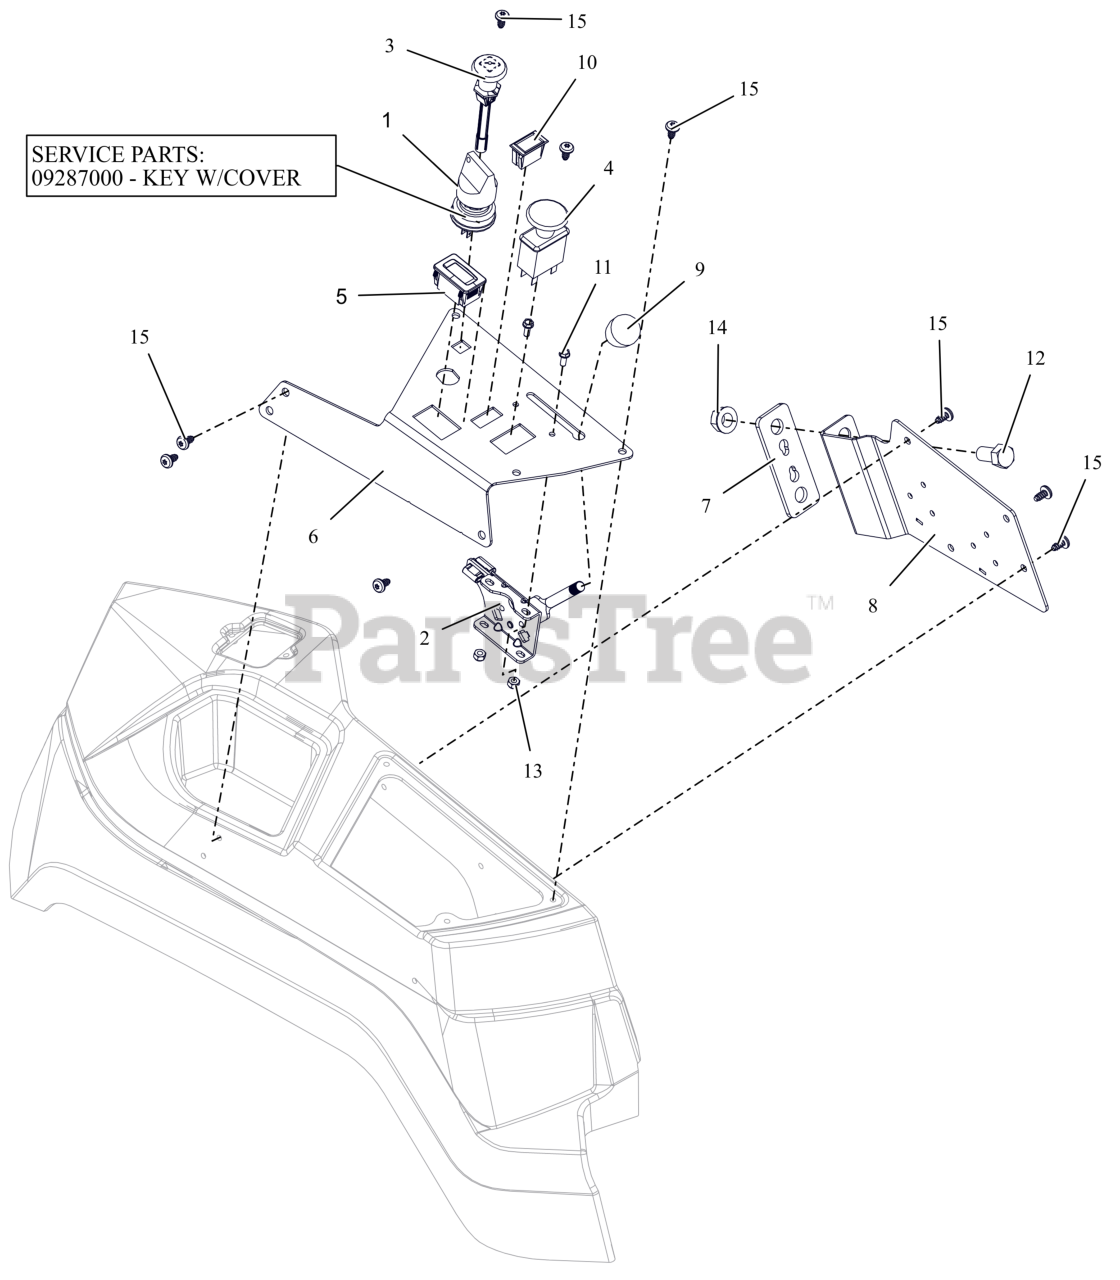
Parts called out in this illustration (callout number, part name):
1	SWITCH, IGNITION
1	KEY, W/ SHIELD
2	CABLE, PRO THROTTLE CONTROL
3	CABLE - CHOKE, SNAP-IN
4	SWITCH, CLUTCH
5	HOUR METER
6	PLATE, APEX CONTROL PANEL
7	PLATE, CONTROL PANEL SPACER
8	BRKT, FENDER/RELAY MOUNTING
9	KNOB-CONTROL-BLACK .38-16X.50
10	SWITCH,BLANK
11	BLT, HWH #10-24X.50 ZCC
12	BLT, HEX .50-13X1.00 G5 ZCC
13	NUT-LK-NYL #10-24 G2 ZCC
14	NUT-LK-TOP-FLG .500-13 GF ZCC
15	SCR-PAN .25-15X.50 6L H/LZB500
